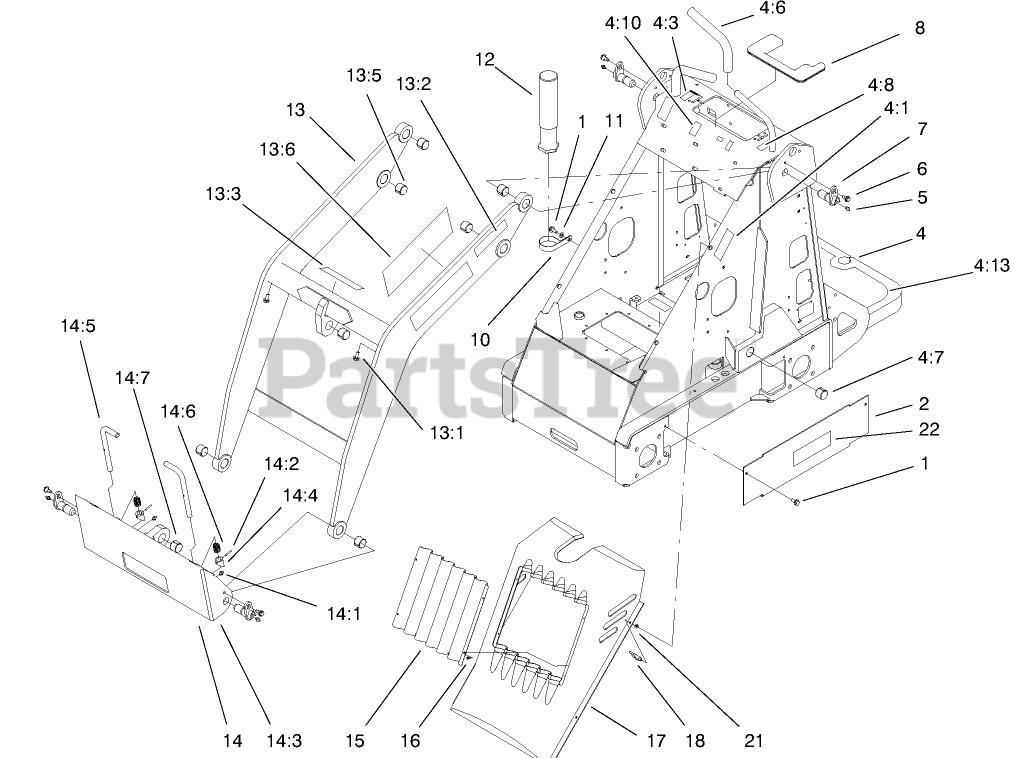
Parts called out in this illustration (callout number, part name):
1	SCREW-HWHTF
2	Cover-Hose
4	Frame & Decal ASM
4:1	DECAL-WARNING, KEEP HANDS AWAY
4:3	DECAL-CHOKE
4:6	GRIP-CUSHION
4:7	BUSHING-TENSION
4:8	DECAL-THROTTLE
4:10	DECAL-SELECTOR
4:13	TREAD-FOOT
5	FITTING-GREASE
6	BOLT-SHOULDER
7	PIN-PIVOT
8	COVER-VALVE
10	CLAMP-R
11	WASHER-PLAIN
12	TUBE-MANUAL
13	Loader ASM
13:1	SCREW-HWHTF
13:2	DECAL-WARNING, KEEP HANDS AWAY
13:3	DECAL-CAUTION
13:5	BUSHING-TENSION
13:6	DECAL-DANGER
14	QUICK ATTACH ASM
14:1	FITTING-GREASE
14:2	PIN-SPECIAL
14:3	MOUNT-ATTACH, QUICK
14:4	CAM-ATTACH, QUICK
14:5	Pin-Quick Attach
14:6	SPRING-COMPRESSION
14:7	BUSHING-TENSION
15	Grille-Screen
16	SCREW-PPH
17	Cover-Hood
18	LATCH-SWELL
21	WASHER
22	DECAL-4-PAW
